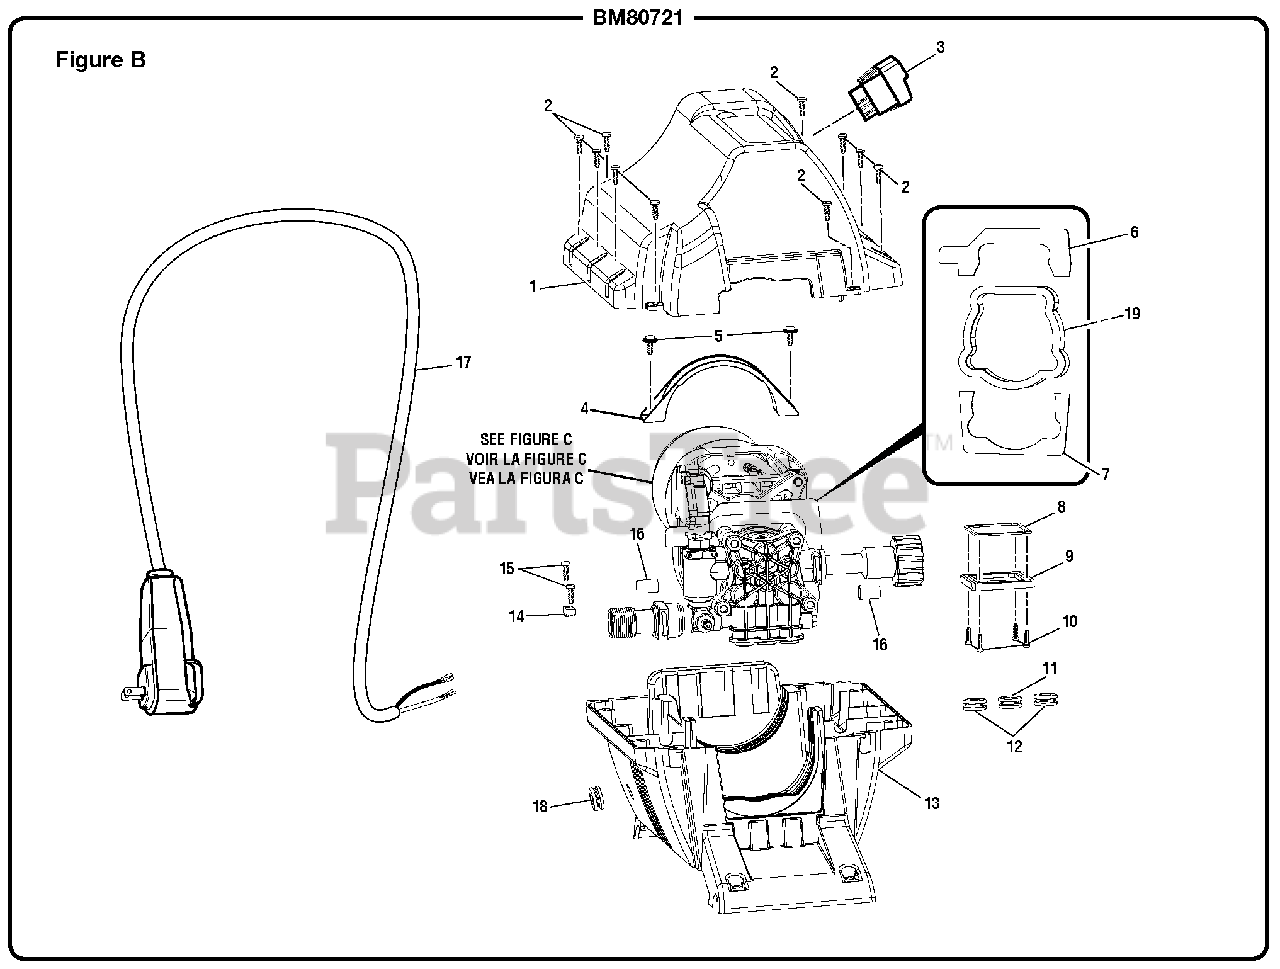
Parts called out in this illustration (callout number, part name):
1	Top Motor Housing
2	Screw (M4 x 15 mm)
4	Motor Bracket
5	Screw (M4 x 12 mm)
6	Upper Gasket
7	Lower Gasket
8	Switch Cover Gasket
9	Switch Cover
10	Screw (M3 x 14 mm)
13	Lower Motor Housing
14	Cord Clamp
15	Screw (M3.5 x 20 mm)
17	Power Cord
